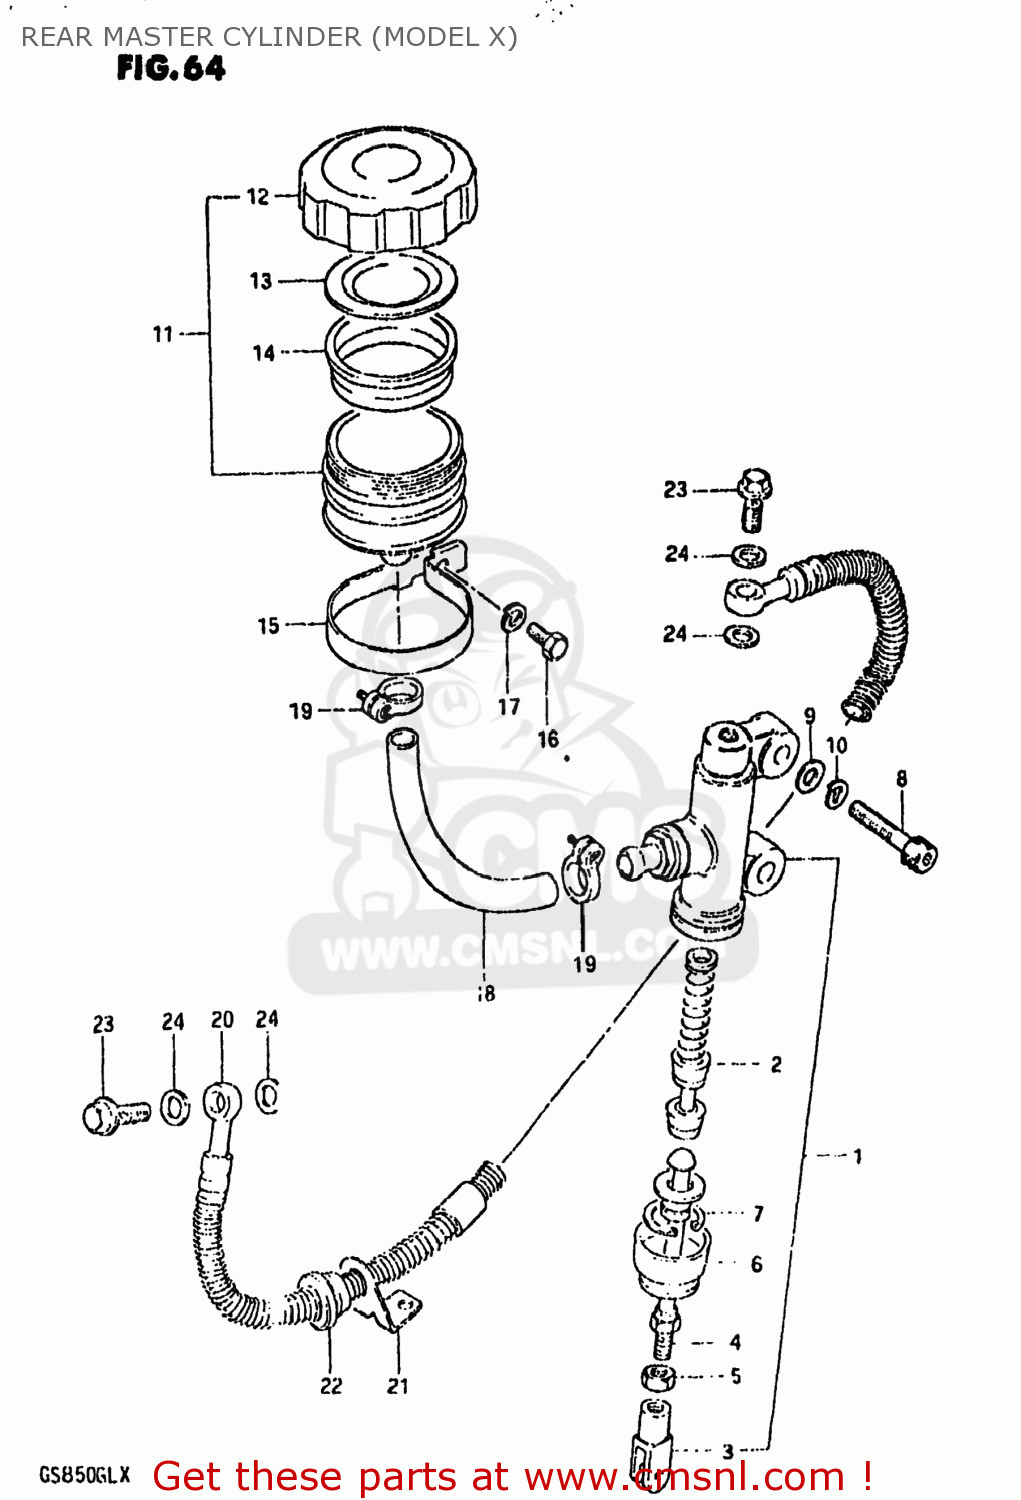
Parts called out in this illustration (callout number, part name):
1	CYLINDER ASSEMBLY,REAR MASTER
2	PISTON/CUP SET
3	YOKE
4	ROD,REAR MASTER CYLINDER
5	NUT
6	BOOT
7	CIRCLIP
8	BOLT
9	WASHER
10	WASHER,LOCK,8.
11	TANK ASSEMBLY,RESERVOIR
12	CAP
13	PLATE,DIAPHRAGM
14	DIAPHRAGM
15	CLAMP
16	BOLT, UPPER
17	LOCK WASHER
18	HOSE,RESERVOIR TANK
19	CLAMP
20	HOSE,REAR BRAKE
21	GUIDE,BRAKE HOSE
22	GROMMET,BRAKE HOSE GUIDE
23	BOLT,UNION
24	WASHER
